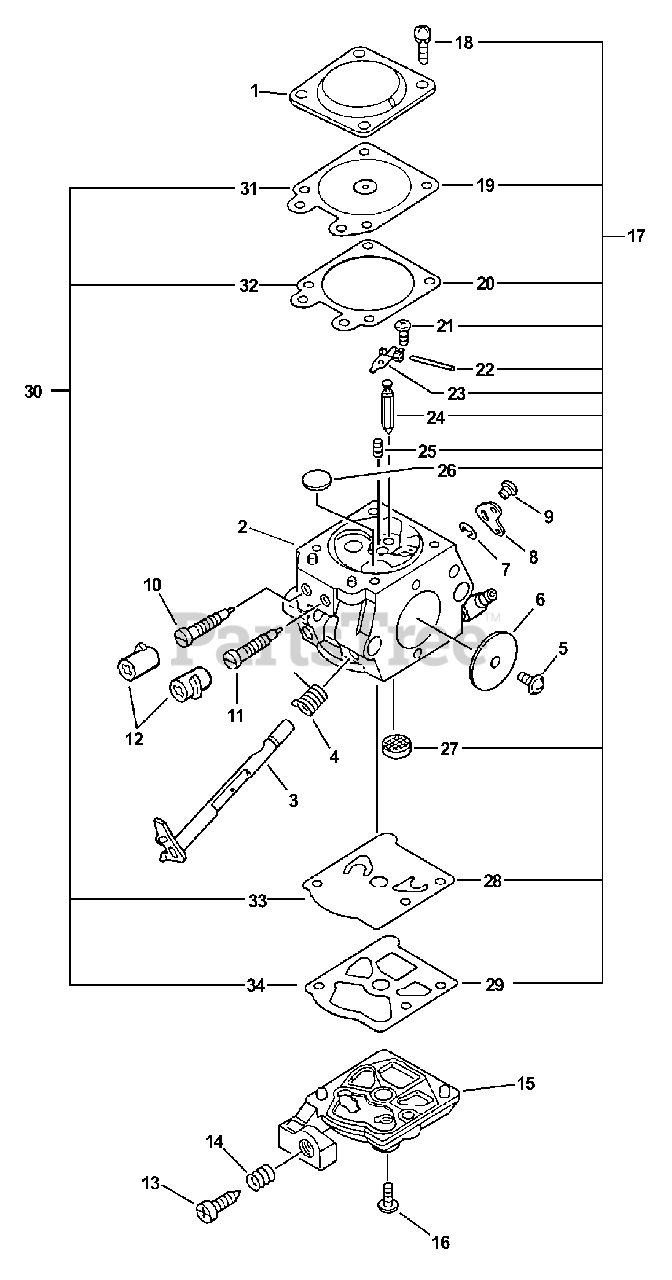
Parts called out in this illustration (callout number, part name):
1	COVER, METERING DIAPHRAGM
2	BODY, CARBURETOR
3	SHAFT, THROTTLE
4	SPRING, THROTTLE
6	VALVE, THROTTLE
8	LEVER, THROTTLE
10	NEEDLE, HIGH SPEED
11	NEEDLE, IDLE
12	CAP, LIMITER
13	SCREW, IDLE ADJUST
14	SPRING, IDLE ADJUST
15	COVER, FUEL PUMP
17	REPAIR KIT, CARBURETOR
19	DIAPHRAGM, METERING
20	GASKET, METERING
21	SCREW, METERING LEVER PIN
22	PIN, METERING LEVER
23	LEVER, METERING
24	VALVE, INLET NEEDLE
25	SPRING, METERING LEVER
26	PLUG, WELCH
27	STRAINER
28	DIAPHRAGM, PUMP
29	GASKET, PUMP
30	GASKET / DIAPHRAGM KIT
31	DIAPHRAGM, METERING
32	GASKET, METERING
33	DIAPHRAGM, PUMP
34	GASKET, PUMP
